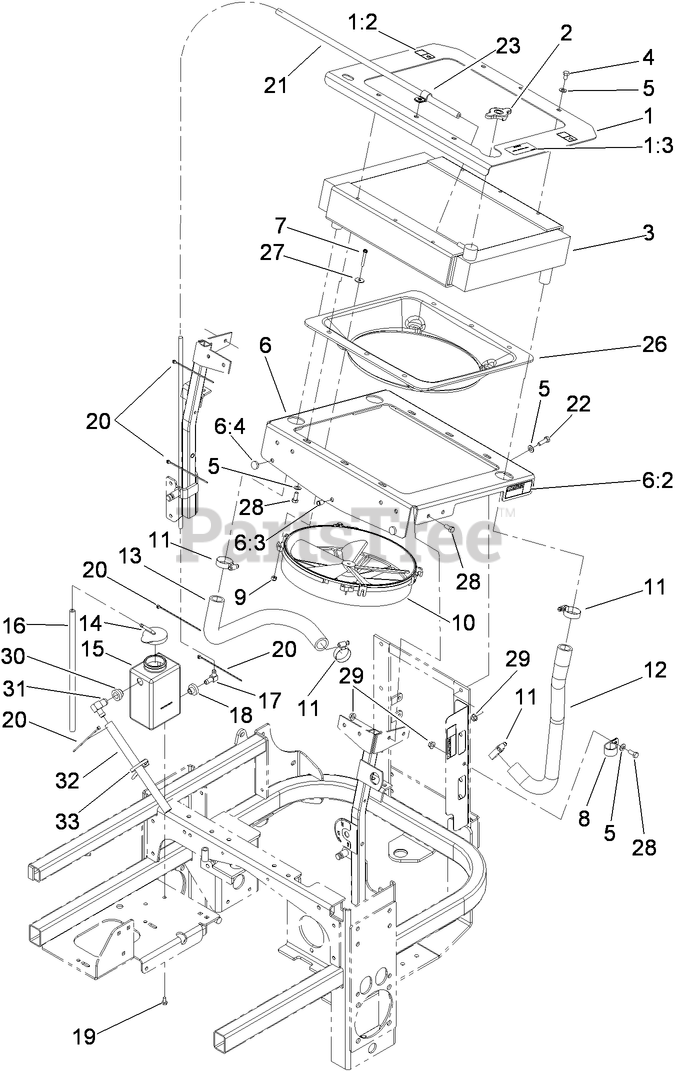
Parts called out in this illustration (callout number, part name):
1	TOP RADIATOR PLATE ASM
1:2	DECAL-SURFACE, HOT
1:3	DECAL-ANTIFREEZE
2	CAP-RADIATOR
3	RADIATOR
4	SCREW-HH
5	WASHER-PLAIN
6	BOTTOM RADIATOR PLATE ASM
6:2	DECAL-DANGER
6:3	NUT-CLINCH
6:4	BUMPER
7	SCREW-HWH
8	CLIP-LOOM
9	NUT-LOCK, HH
12	HOSE-RADIATOR, LH
13	HOSE-OUTLET, ENGINE
14	CAP-TANK, OVERFLOW
15	TANK-OVERFLOW
16	HOSE-LINE, FUEL
19	SCREW-HH
20	TIE-CABLE
21	HOSE-OVERFLOW
22	SCREW-HH
23	CLIP-LOOM
26	SHROUD-COOLING, ENGINE
27	WASHER
28	SCREW-HH
29	NUT-HF
31	FITTING-ELBOW
32	HOSE-OVERFLOW
33	TIE-PLASTIC
